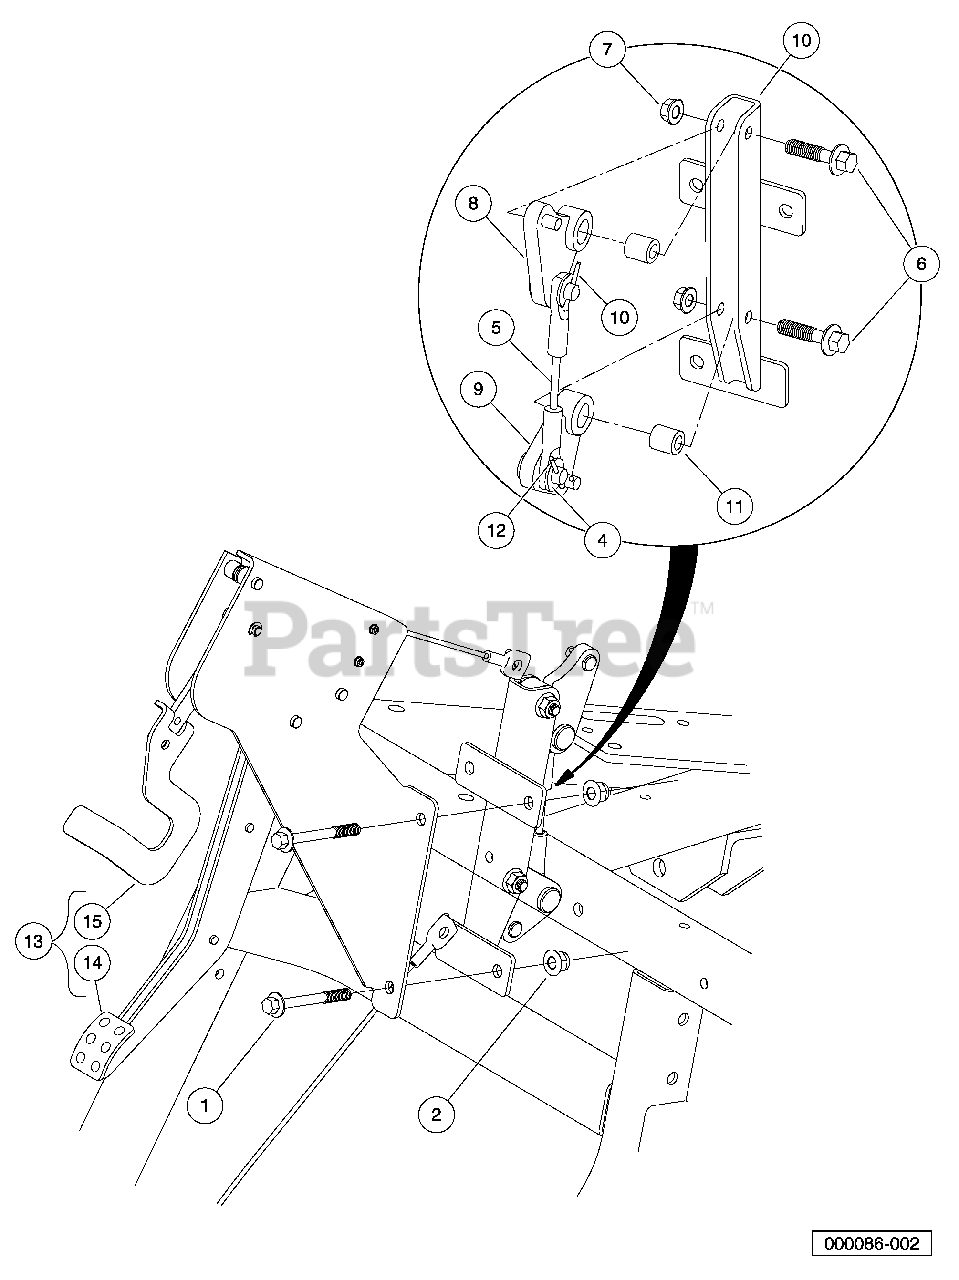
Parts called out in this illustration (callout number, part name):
1	Bolt Flanged Head, M8 X 1.25 X 65.
2	Lock Nut, Flg M8 X 1.25 Nylon
3	Asm, Sub, Bracket, Park Brake
4	Washer, Flat, 3/8, Blk Fin
5	Cable, Crank, Bell
6	Bolt Flg, M8x1.25 X 35, Gr10.9.
7	Nut Flg M8 X 1.25 Gr 10
8	Asm, Bellcrank, Upper
9	Asm, Bellcrank, Lower
10	Brkt, Bellcrank, Prk Brk, Awd
11	Spacer, Pivot, Park Brk, Awd
12	Cotter Pin, 3/32 x 1.
13	Asm, Pedal, Brake, Hard
14	Pedal, Brake, Park
15	Handle, Release, Park Brake
